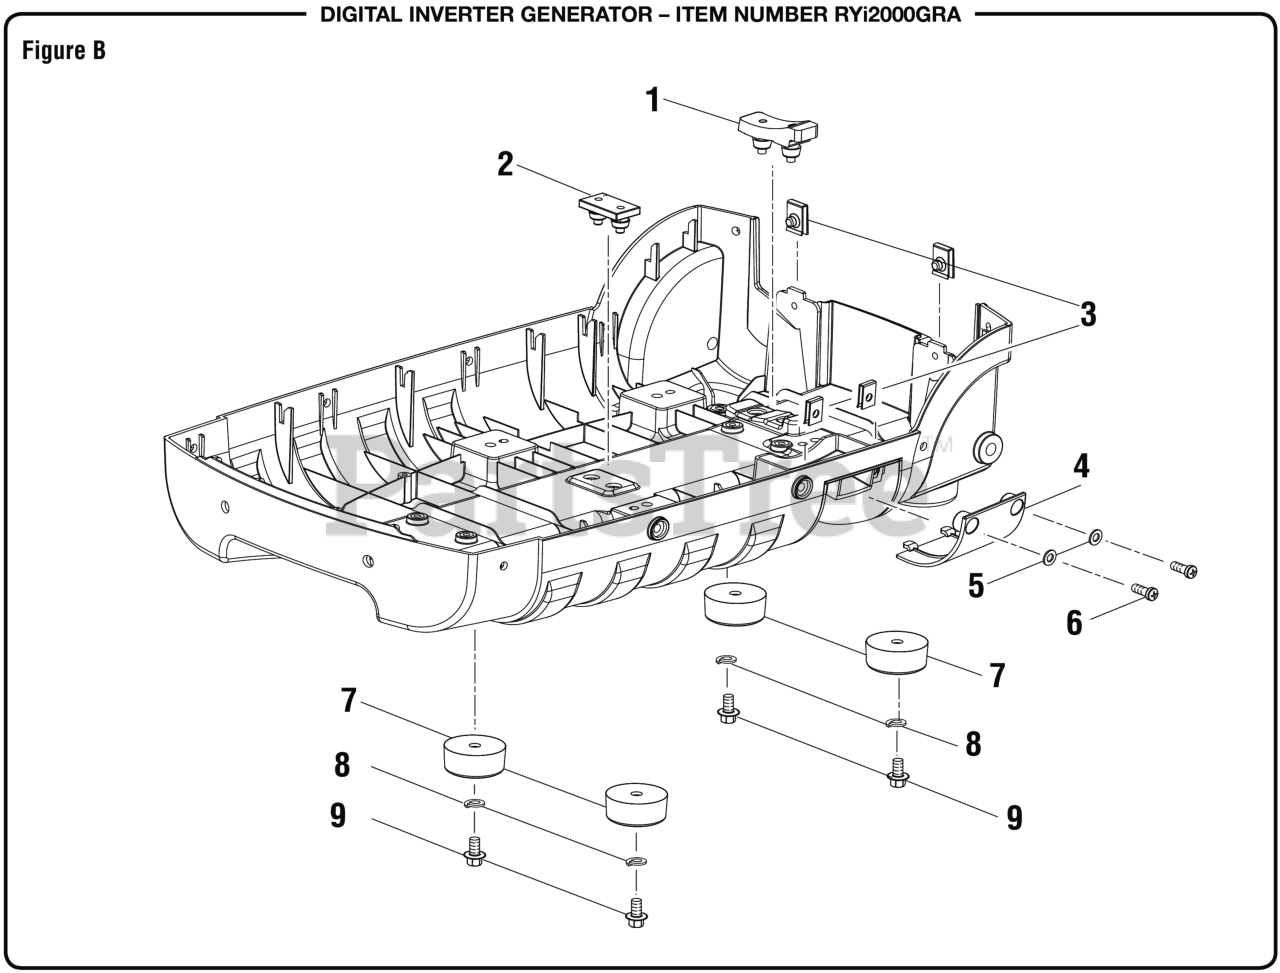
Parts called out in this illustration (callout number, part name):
1	Engine Support Isolator (Back)
2	Engine Support Isolator (Front)
3	U-Clip (M5)
4	Oil Drain Door
5	Washer (ID5.3 x OD10 x 1t)
6	Screw (M5 x 12 mm, Phillips Pan Hd)
7	Isolator Foot
8	Lock Washer (1/4 in.)
9	Bolt (M6 x 12 mm, Hex Hd.)
